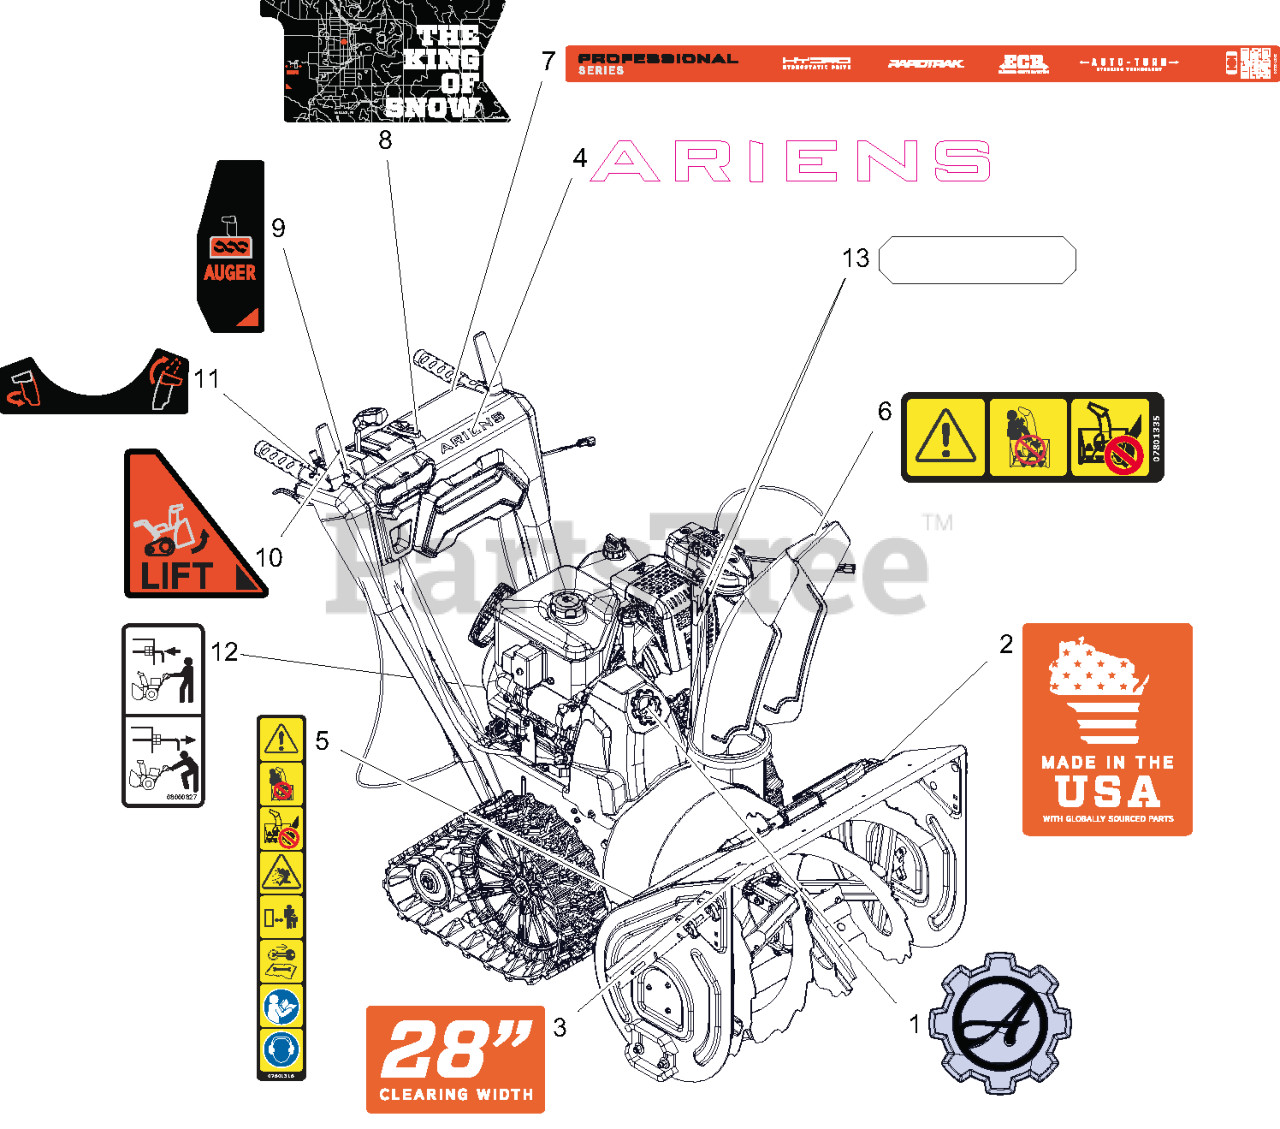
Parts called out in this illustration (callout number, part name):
1	DECAL, ARIENS - GEAR BADGE
2	DECAL- MADE IN USA
3	DECAL- CLEARING - 28
4	DECAL- ARIENS - 7.46"
5	DECAL- SAFETY - DANGER
6	DECAL- DANGER
7	DECAL- DASH - PRO TRK
8	DECAL- CONTROL - LG
9	DECAL- CONTROL - AUGER
10	DECAL- CONTROL - TRACK LIFT
11	DECAL- CONTORL - ECR
12	DECAL, BYPASS
13	DECAL,REFLECTIVE,GEAR COVER
